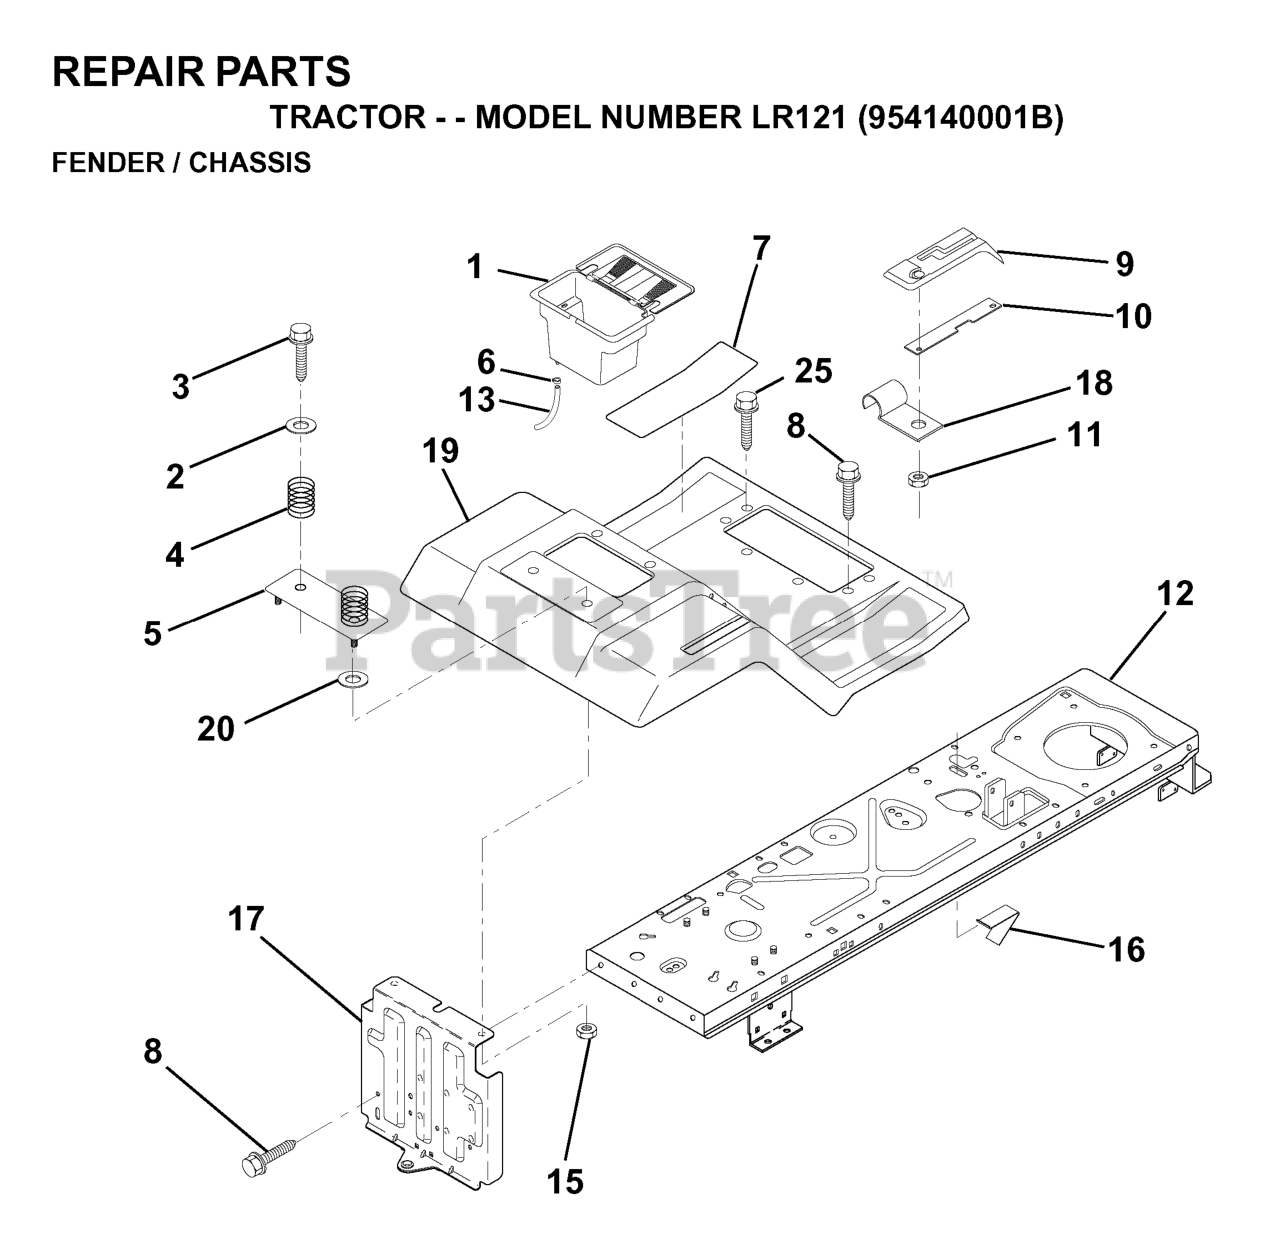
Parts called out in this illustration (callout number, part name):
1	CASE BATTERY MECH HINGE
2	WASHER
3	SCREW
4	SPRING COMPRESSION
5	PLATE ASM BATTERY
6	HOSE CLAMP T
7	PAD FOOTREST
8	SCREW.THDROL.5/16-18X3/4.TTY
9	CONSOLE SHT CONTR
10	BAR, SHIFT LOCK
11	NUT.PUSH.3/16
13	TUBE BATTERY DRAIN
15	Nut, Keps Blk Hex 1/4-20 UNC
16	SWITCH ACTUATOR
18	CLIP,INSULATOR
19	FENDER/FOOTREST
20	WASHER
25	Screw Hex Wsh Thdroll 5/16-18 x 1
